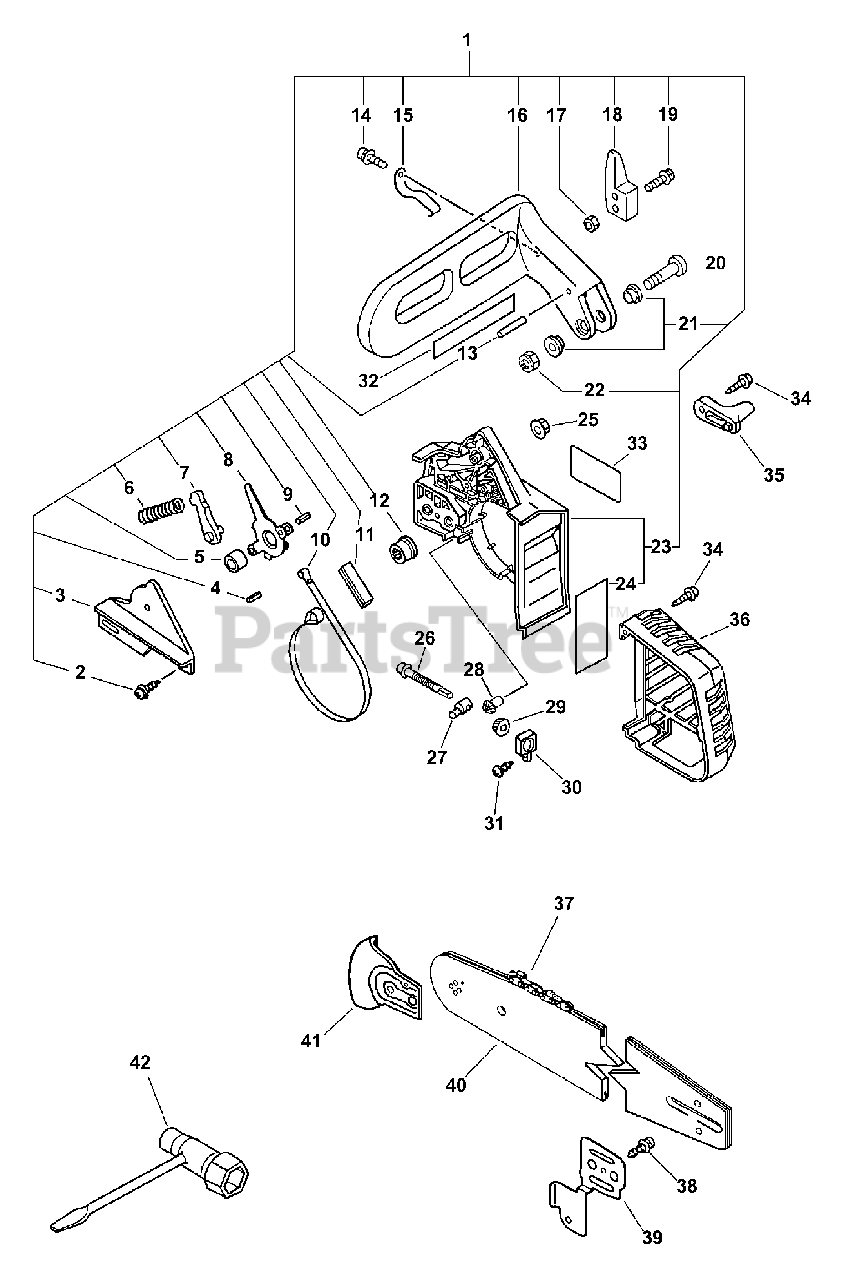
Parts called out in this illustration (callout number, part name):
1	CHAIN BRAKE ASSY
2	SCREW - 4X12 -- TAPPING
3	COVER, BRAKE - GRAY
4	PIN - SPRING -- 2.5X12
5	SPACER - 8
6	SPRING, BRAKE
7	STOPPER, BRAKE
8	LEVER, BRAKE
9	PIN - SPRING -- 4X8
10	BAND, BRAKE
12	ADJUSTER, BRAKE BAND
13	ROLLER - 4X23.8
14	SCREW - 4X12 -- TAPPING
15	SPRING, RETURN
16	LEVER, BRAKE - ORANGE
18	WEIGHT, BRAKE
19	SCREW - 4X22
20	SCREW - 5X32
22	LOCKNUT - 5
23	GUARD, SPROCKET - GRAY
24	DEFLECTOR, HEAT
25	NUT - 6 -- FLANGE
26	SCREW, TENSIONER
27	TENSIONER, CHAIN
28	GEAR - PINION
29	GEAR - BEVEL
30	BRACKET, TENSIONER
31	SCREW - 4X12 -- TAPPING
32	LABEL - BAR & CHAIN
33	LABEL - MODEL CS-300
34	SCREW - 5X20 -- TAPPING
35	CATCHER, CHAIN
36	COVER, EXHAUST
37	SAW CHAIN - 12" (30cm)
37	SAW CHAIN - 14" (35cm)
37	SAW CHAIN - 16" (40cm)
38	SCREW - 4X10
39	PLATE, GUIDE - OUTER
40	GUIDE BAR - 12" (30cm)
40	GUIDE BAR - 14" (35cm)
40	GUIDE BAR - 16" (40cm)
41	KICK GUARD KIT
42	T-WRENCH - 10X19mm
